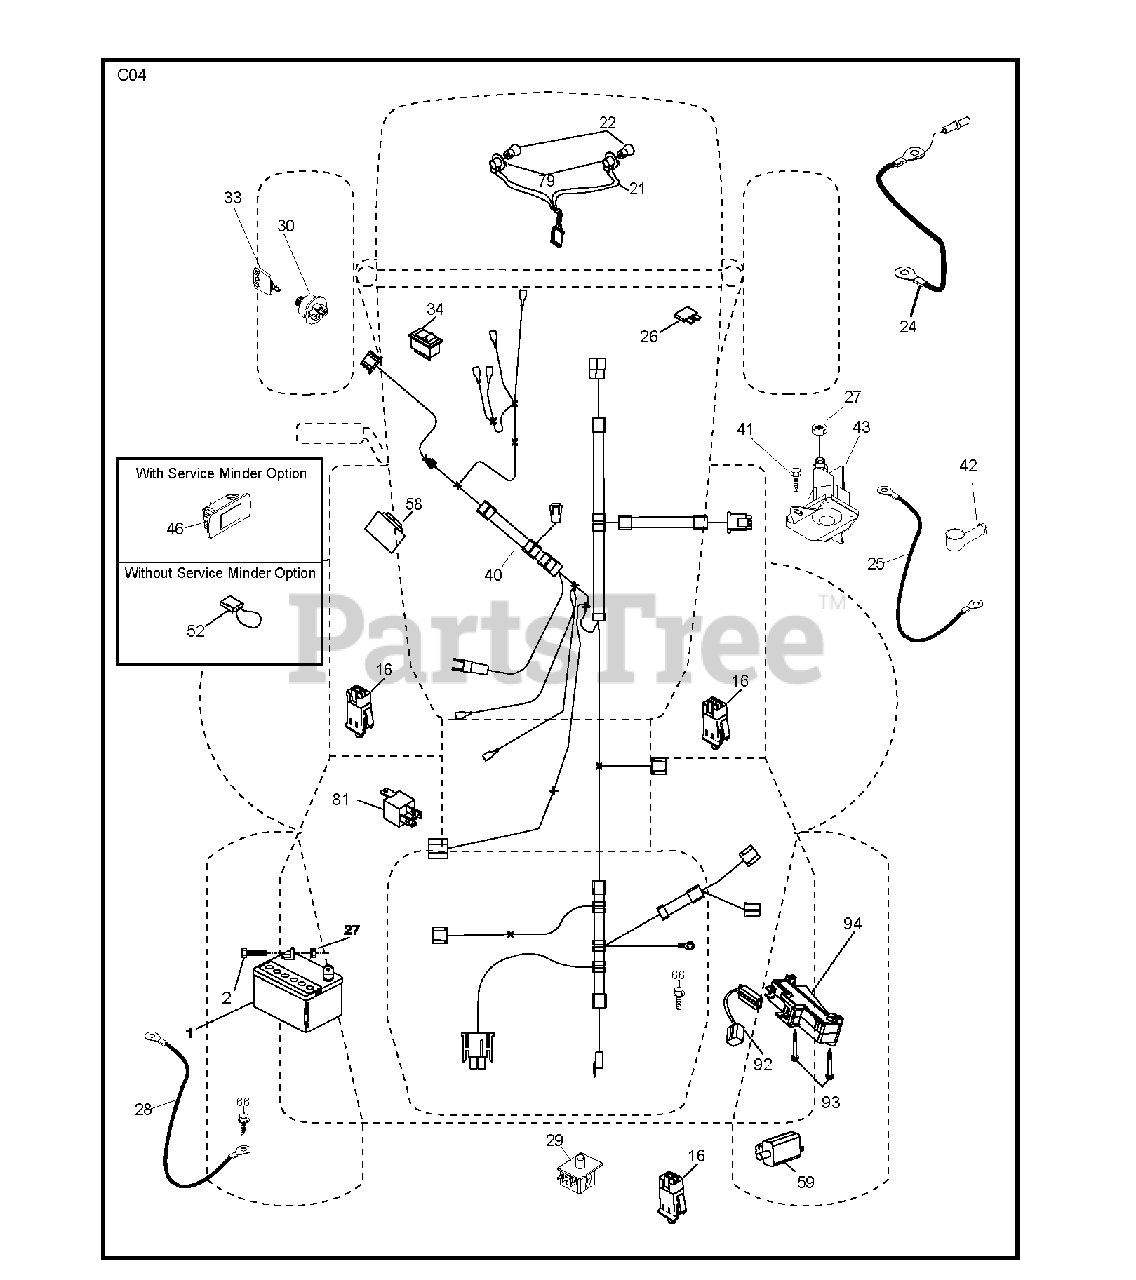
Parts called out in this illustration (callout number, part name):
1	REPL BY 532 12 38-99
16	SWITCH INTERLOOK PUSH-IN
21	HARNESS ASSY LIGHT
22	LIGHTBULB
24	CABLE BATTERY
25	CABLE BATTERY 6 GA. 11" RED
26	FUSE 20AMP
27	NUT
28	CABLE GROUND
29	SWITCH.SEAT.DP W/RAMPS
30	SWITCH.IGN.DELTA.W.LGH.ROS
33	KEY.CHAIN.BLISTER.PACK.GEN.INT
34	SWITCH LT
42	TERMINAL COVER
43	SOLENOID.W/BRASS.PLUNG
46	GUAGE.SRVCMNDR.HRMTR.
58	BUZZER
79	BULB HOLDER ASM.
81	RELAY.ASSY.T
92	HARNESS.PIGTAIL.CONSLE
93	SCREW.PLASTITE
94	MODULE.REVERSE.ROS
